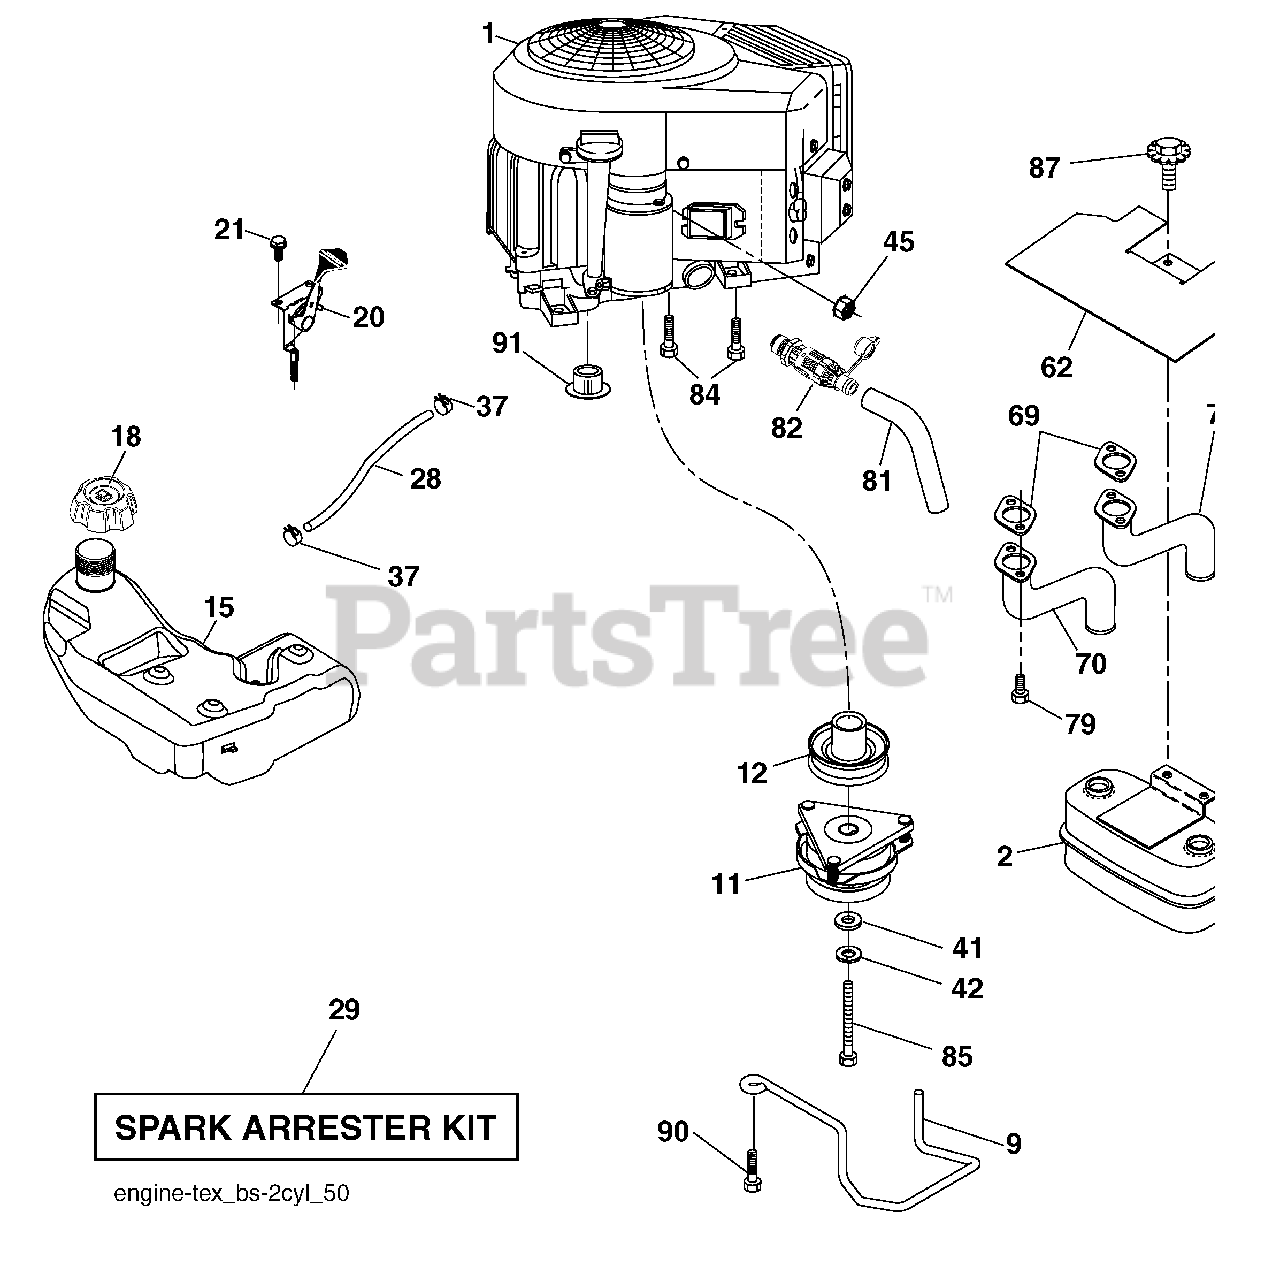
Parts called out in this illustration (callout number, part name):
9	Keeper Belt Engine
11	Clutch Electric
12	Pulley Engine
15	Tank Fuel
18	Cap Asm
20	Control Throttle
21	Screw #10 x 0.750 BOS Thread
28	Fuel Line
29	Spark Arrester Kit
37	Clamp Hose
41	Washer 1-1/2 OD x 15/32 ID x .250
42	Washer Lock 7/16
45	Nut Keps Hex 1/4-20 unc
62	Shield Heat Muffler
70	Tube Exhaust LH
71	Tube Exhaust RH
79	Screw Socket Head 5/16-18 x 1
81	Tube Drain Oil Easy
82	Valve Oil Drain
84	Screw 3/8-16 x 1-1/4
85	Bolt Hex 7/16-20 x 4 Gr. 5
87	Bolt 5/16-18 unc x 1 w/Sems
90	Screw 3/8-16 x 1
